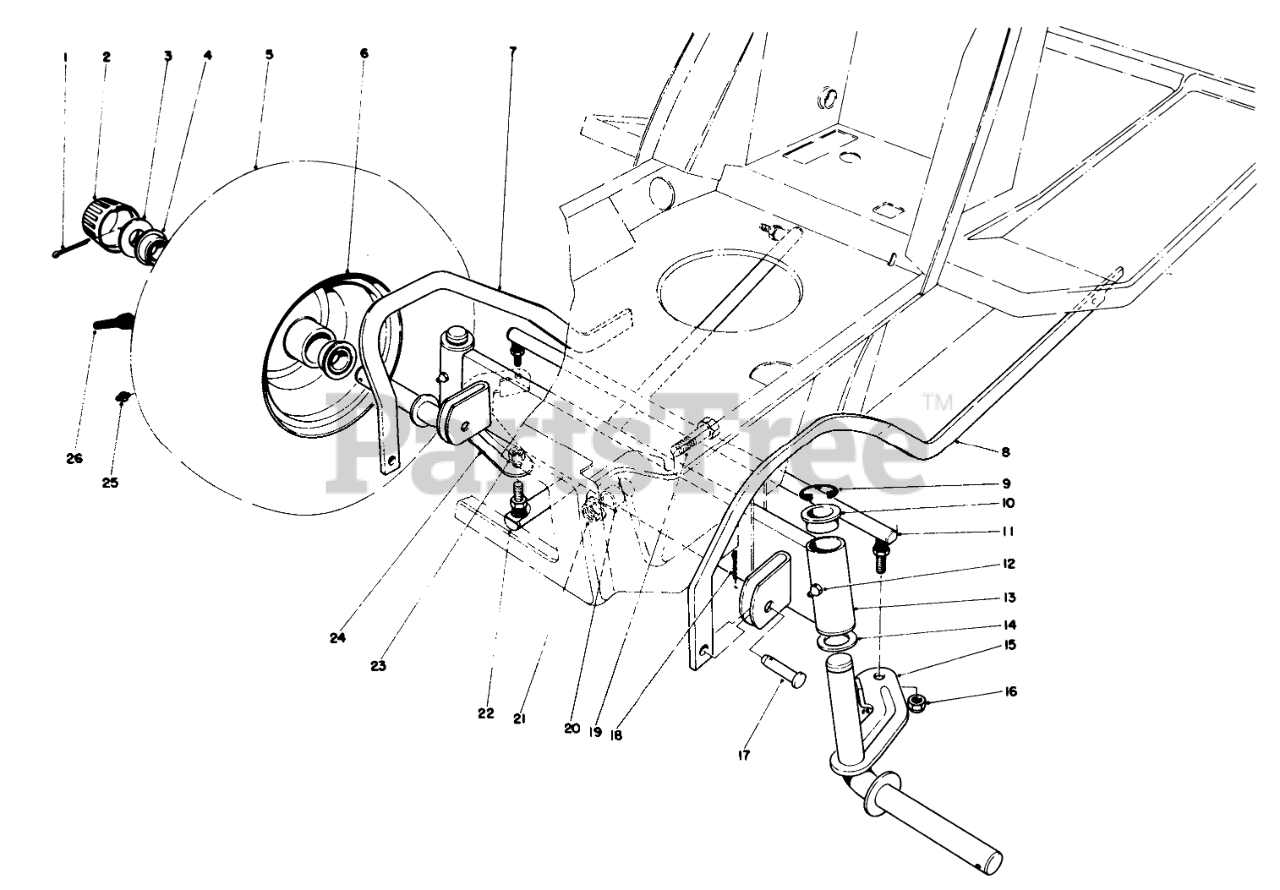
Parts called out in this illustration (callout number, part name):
1	PIN-COTTER
2	Cap-Hub
3	WASHER-PLAIN
4	Bearing
5	TIRE-FRONT
6	FRONT WHEEL
7	RH DECK PARALLEL LINK R
8	LH DECK PARALEL LNKR
9	E-RING
10	BEARING-FLANGE
11	Tie Rod Steering
12	GREASE FITTING
13	Front Axle (Incl. Ref. #10)
14	WASHER-THRUST
15	Spindle L.H.
16	NUT-LOCK NI
17	PIN-CLEVIS
18	PIN-COTTER
19	SCREW-HH
20	SPACER-AXLE, FRONT
21	NUT-HF
22	STEERING ARM B
23	Nut
24	SPINDLE WA RH B
25	FITTING-GREASE
26	STEM-VALVE
